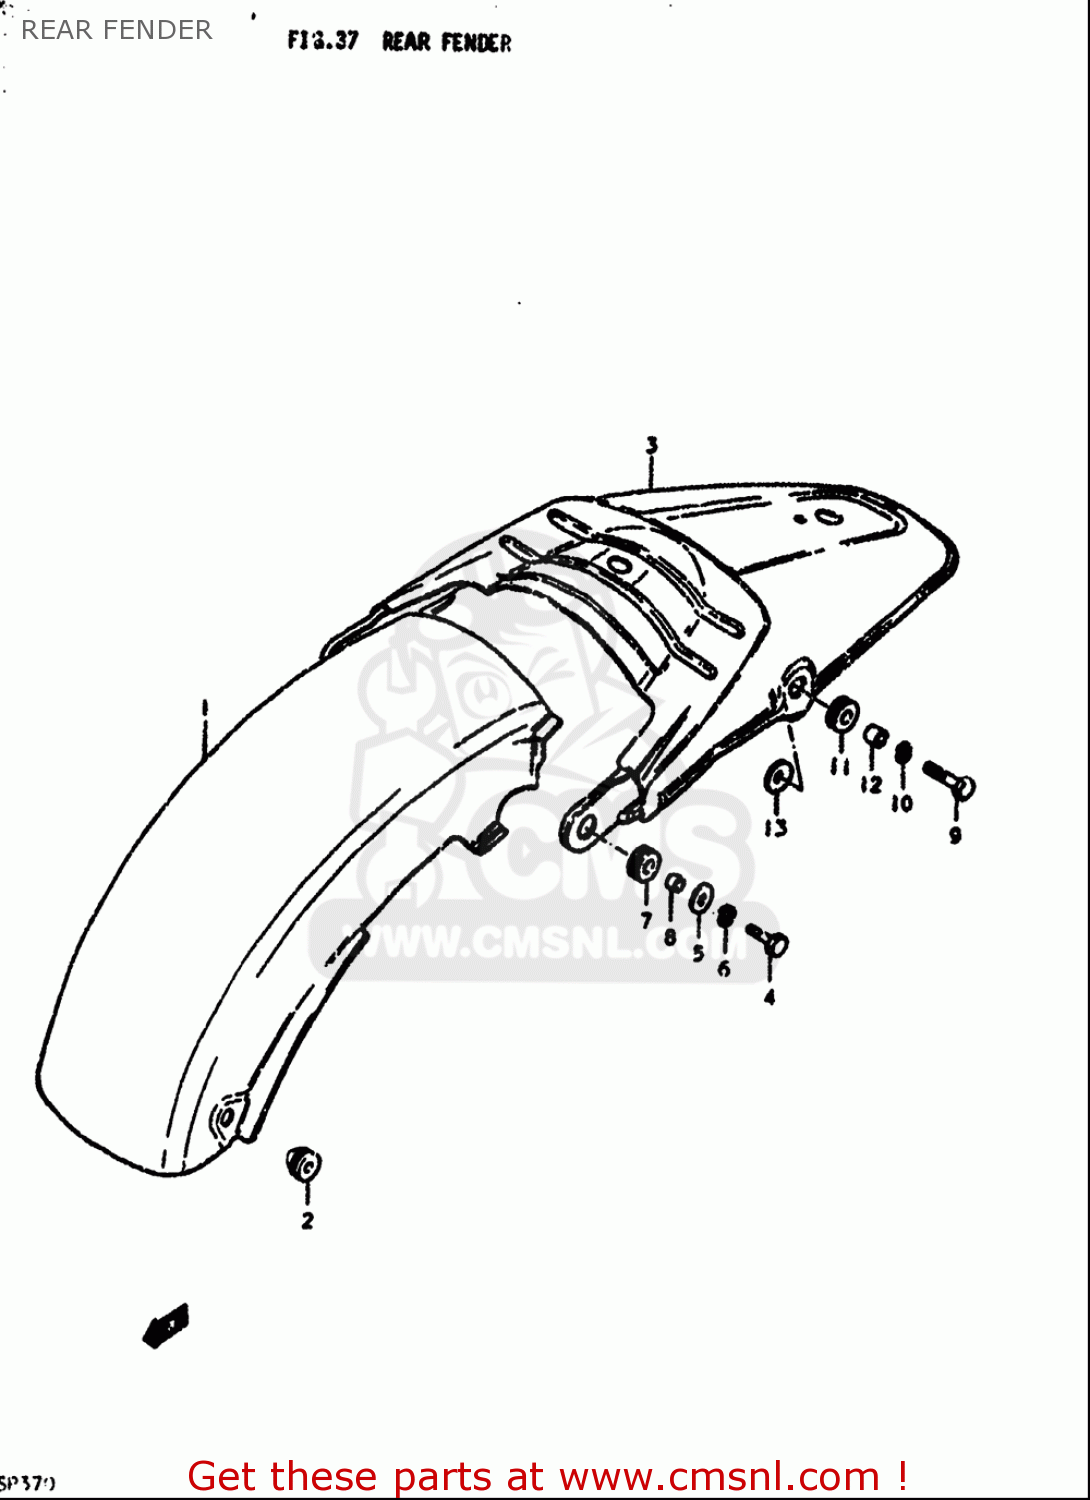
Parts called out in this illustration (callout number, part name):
4	BOLT
5	WASHER(6.5X20X1.2)
6	WASHER,LOCK
7	CUSHION
8	SPACER(6.1X9X7.5)
9	BOLT
10	WASHER,LOCK
11	CUSHION
12	SPACER(8.2X10X8)
13	WASHER(8.5X24X1.6)
